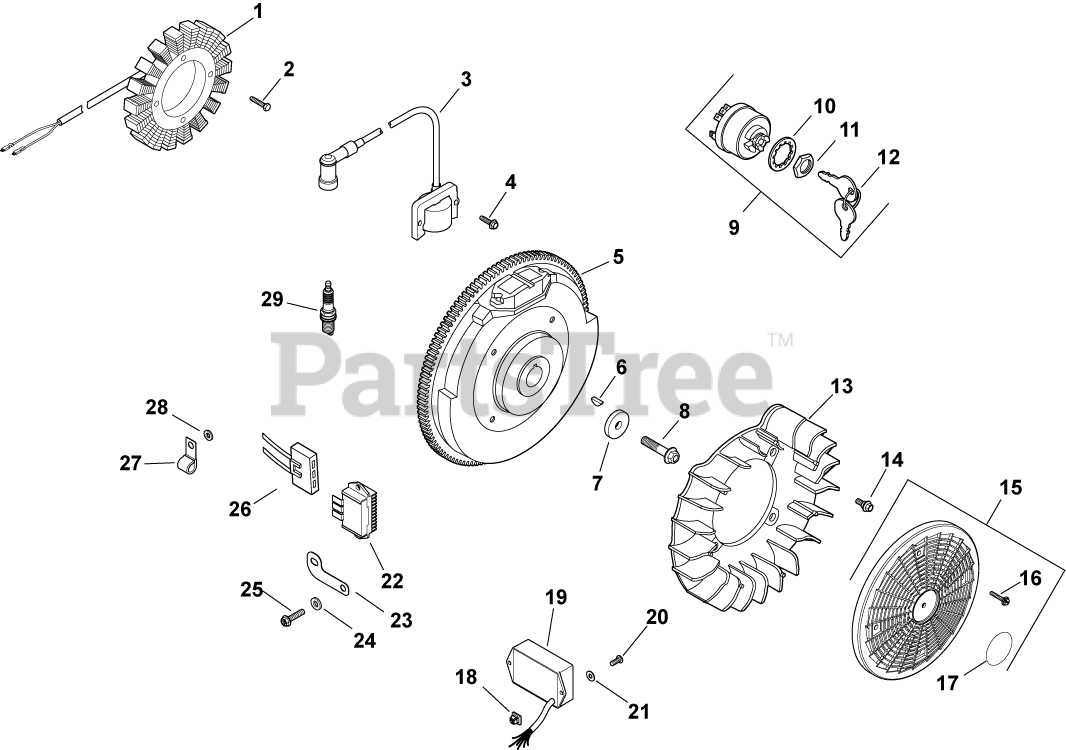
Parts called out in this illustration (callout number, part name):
1	KIT, 15 / 20 AMP STATOR
2	SCREW, M5X0.8X25 - (#25086402S)
3	MODULE, IGNITION
4	SCREW, FLG THD FRM M5X.8X20-(#25086399S)
5	FLYWHEEL ASSEMBLY-USE 24 025 58-S
6	KEY, 3/16" X 5/8"
7	WASHER, FLAT 13/32"
8	SCREW, FLG M10X1.5X45 - (#25086361S)
9	SWITCH ASSY, KEY (KM)-USE 25 099 32-S
10	WASHER, INTERNAL TOOTH
11	NUT, KEY SWITCH
12	KEY, SET OF 2
13	FAN USE 24 755 253-S
14	BOLT, SHOULDER
15	KIT, GRASS SCREEN
16	SCREW, FLG SEMS M4X.7X25
17	DECAL, GRASS SCREEN USE 24 113 499-S
18	NUT, PLASTIC
19	MODULE, SPEED ADVANCE -USE 24 584 34-S
20	SCREW, PHL HD #11-16X1/2"
21	WASHER, FLAT 1/4" (O.D. 1/2")
22	REG/RECT-15 AMP (KM)-USE 41 403 10-S
23	BRACKET, GROUND STRAP USE 24 518 12-S
24	WASHER, FLAT 7/32"
25	SCREW, PHL HD #11-16X7/8"
26	CONNECTOR, BODY (KM)-USE 25 155 41-S
27	CLIP, CABLE
28	WASHER, FLAT 1/4" (O.D. 1/2")
29	PLUG, SPARK (STD)
